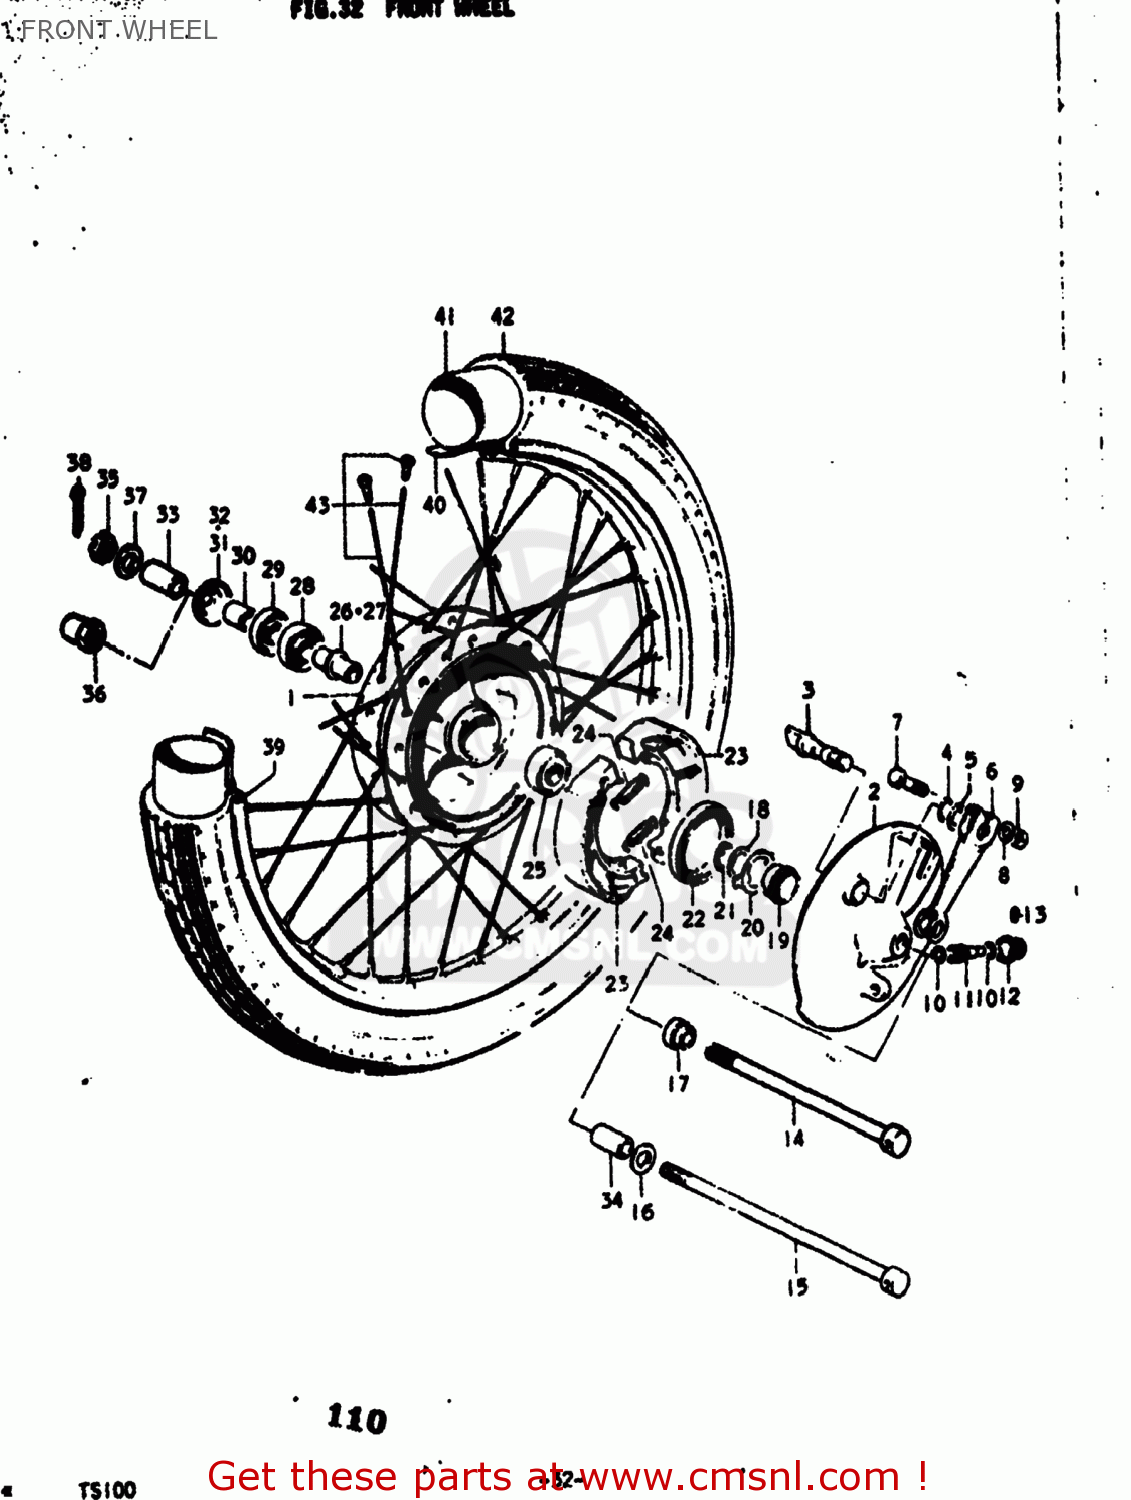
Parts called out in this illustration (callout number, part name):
1	HUB,FRONT
2	PANEL,FRONT HUB
3	CAM,FR BRAKE
4	O RING(D:2.5,ID:11.4)
5	WASHER(12.5X20X1)
6	LEVER,FRONT BRAKE CAM
7	BOLT
8	WASHER
9	NUT
10	WASHER (5.1X9X0.4)
11	PINION,SPEEDOMETER
12	BUSH,METER GEAR OUTER
13	SCREW
14	AXLE,FRONT
15	AXLE,FRONT
16	WASHER
17	SPACER,FRONT AXLE,LEFT
18	WASHER(18.5X24X1)
19	GEAR,SPEEDOMETER
20	DRIVER,SPEEDOMETER GEAR
21	CIRCLIP
22	SEAL,OIL(48X62X7)
23	SHOE,BRAKE
24	SPRING(L:34)
25	BEARING, LH
26	SPACER (12.6X19X52)
27	SPACER,FRONT HUB BEARING
28	BEARING
29	OIL SEAL
30	SPACER
31	DUST SEAL,FRONT HUB DRUM
32	DUST SEAL,FRONT HUB DRUM
33	SPACER (12X20X44)
34	SPACER (12X20X41)
35	NUT 12MM
36	NUT,FRONT AXLE
37	WASHER
38	COTTER PIN
39	RIM,FRONT WHEEL
40	PROTECTOR,WHEEL,INNER
41	TUBE 2.75-19 070-483MM
42	TIRE 2.75-19 070-483MM
43	SPOKE SET,FRONT
